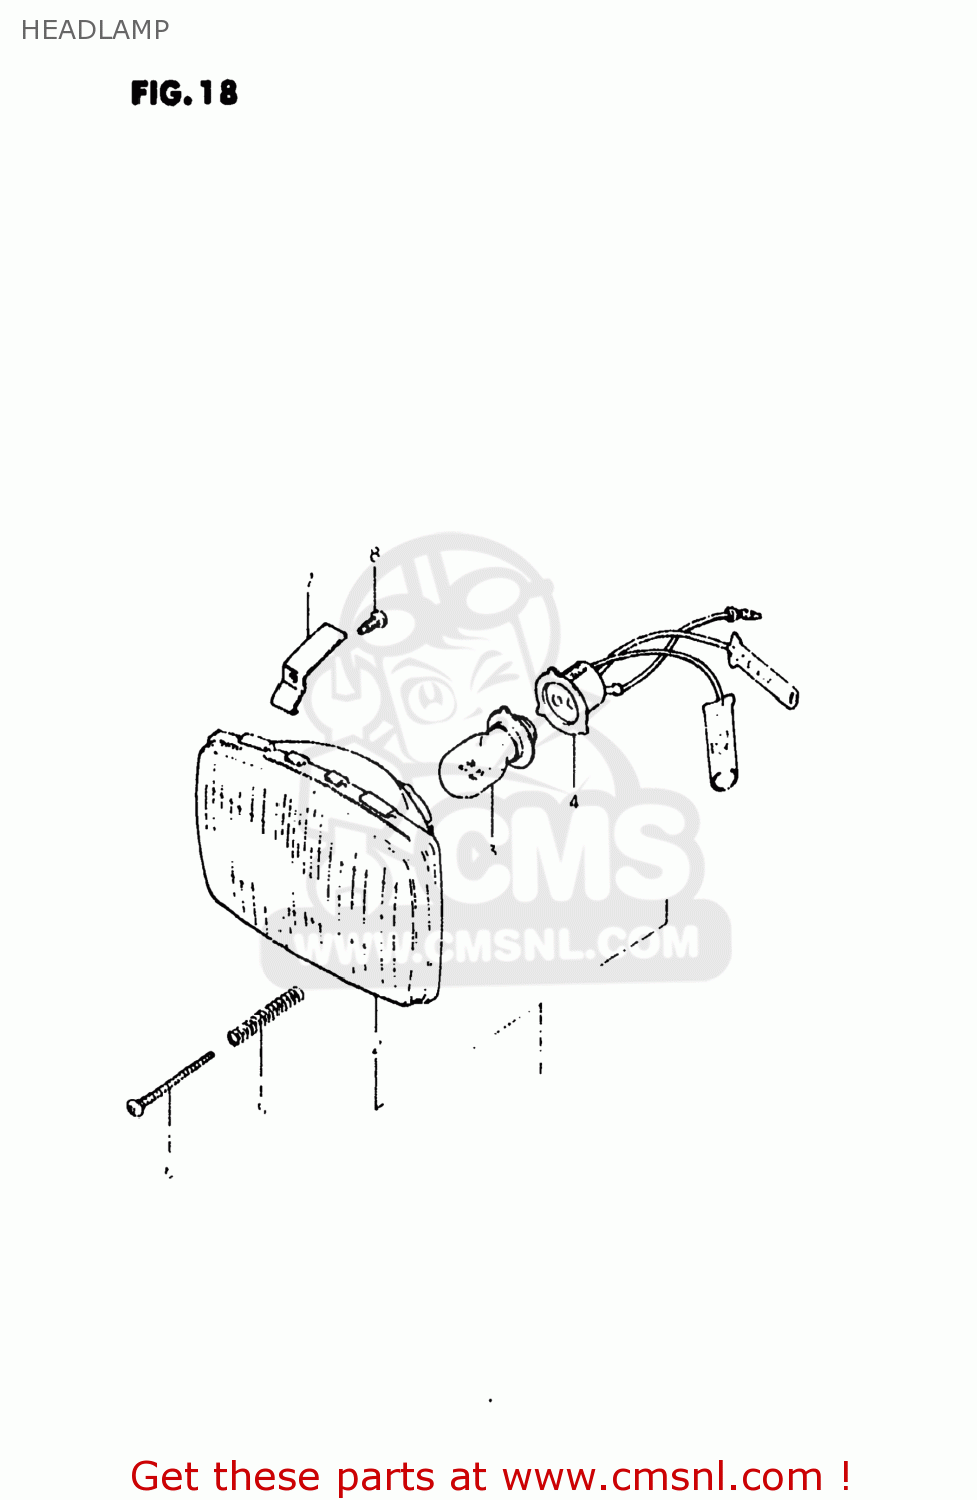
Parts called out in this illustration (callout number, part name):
1	HEADLAMP ASSEMBLY
2	LAMP UNIT
3	BULB(6V15/15W/STANLEY,A3598HA)
4	SOCKET,HEADLAMP
5	SPRING,HEAD LAMP ADJUSTER
6	SCREW,HEADLAMP ADJUST
7	SPRING
8	SPRING,HEADLAMP ADJUST
